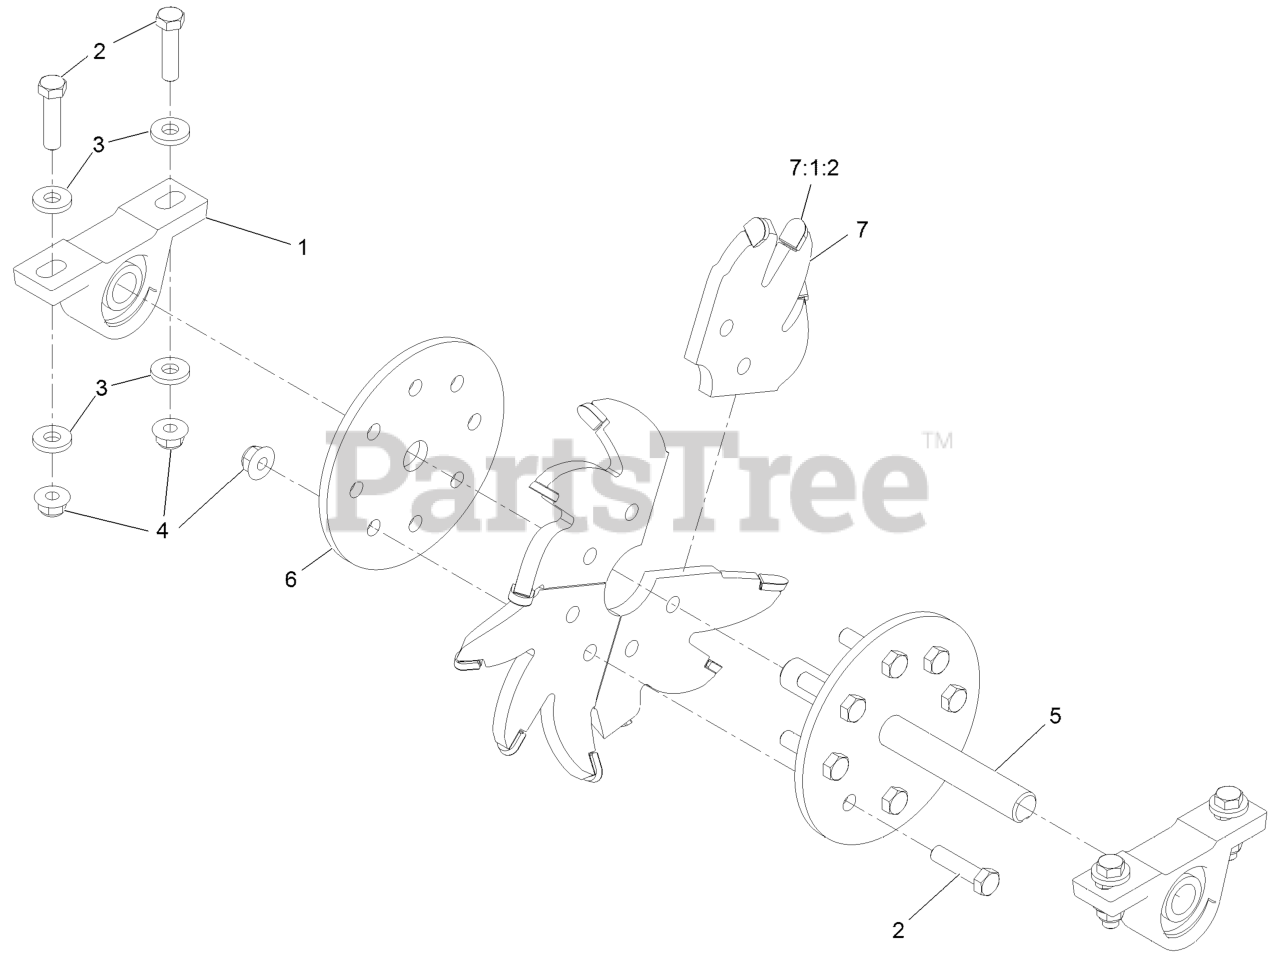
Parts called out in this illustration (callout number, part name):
1	BEARING
2	SCREW-HH
4	NUT-HF, NI
5	BLADE SHAFT ASM
6	PLATE-FLANGE, SHAFT
7:1:2	TIP-CARBIDE
